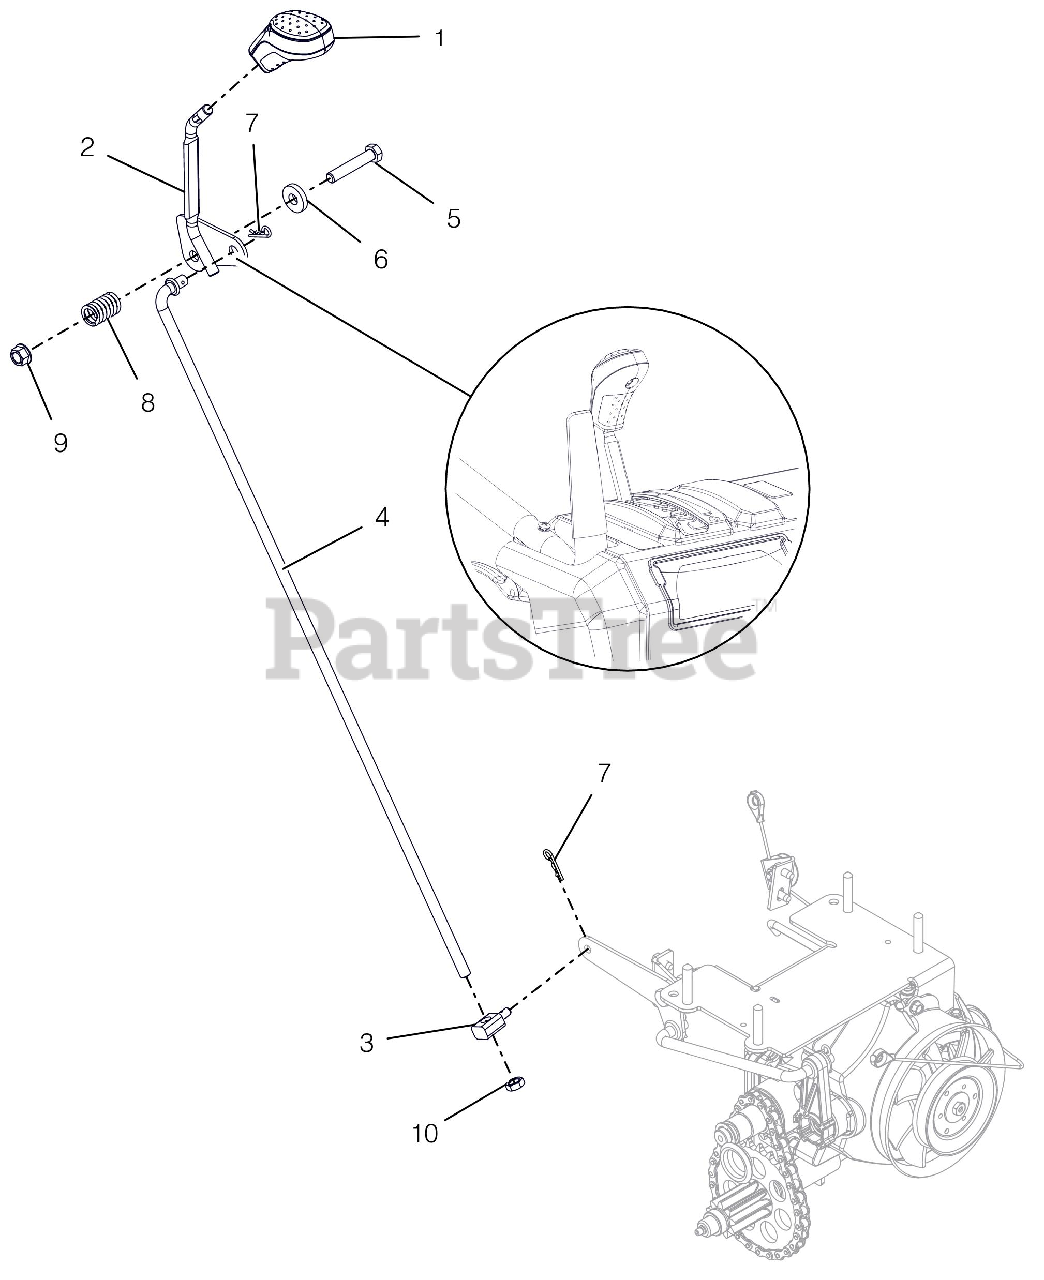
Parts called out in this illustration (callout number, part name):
1	KNOB, CONTROL, DASH
2	WELDMENT,LG DASH SPEED CONTROL
3	PIVOT,SHIFT ROD .375-16(TRUNN)
4	ROD, SHIFT-PRO
5	@BLT-HEX .38-16X2.00 GR5 YWZC
6	WSHR-FL-STL .406X1.00X.188 YWZ
7	PIN-HAIR INT .08X.18X1.18 YWZC
8	SG-COMP .125X.781X1.250
9	@NUT-LK-TOP-FLG .38-16 YWZC
10	NUT-HEX-JAM .375-16 YWZC
